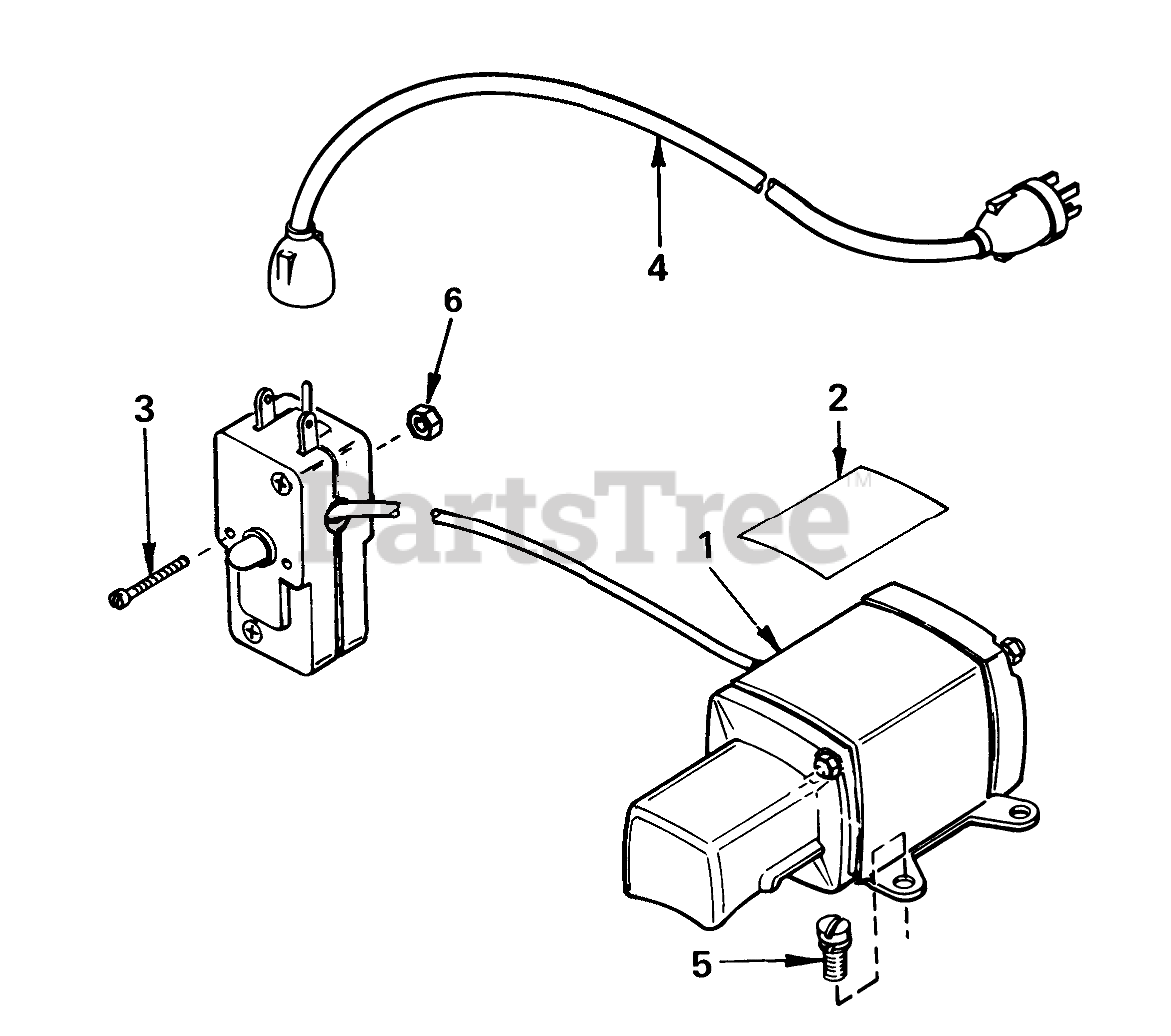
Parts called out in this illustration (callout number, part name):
1	Motor, Cranking (CSA Approved) (Incl. #2 thru 6)
2	Decal
3	Screw, Pan Hd.
4	Cord-Extension
5	Screw (T-30, 1/4-20 x 23/32)
6	Nut & Lockwasher
